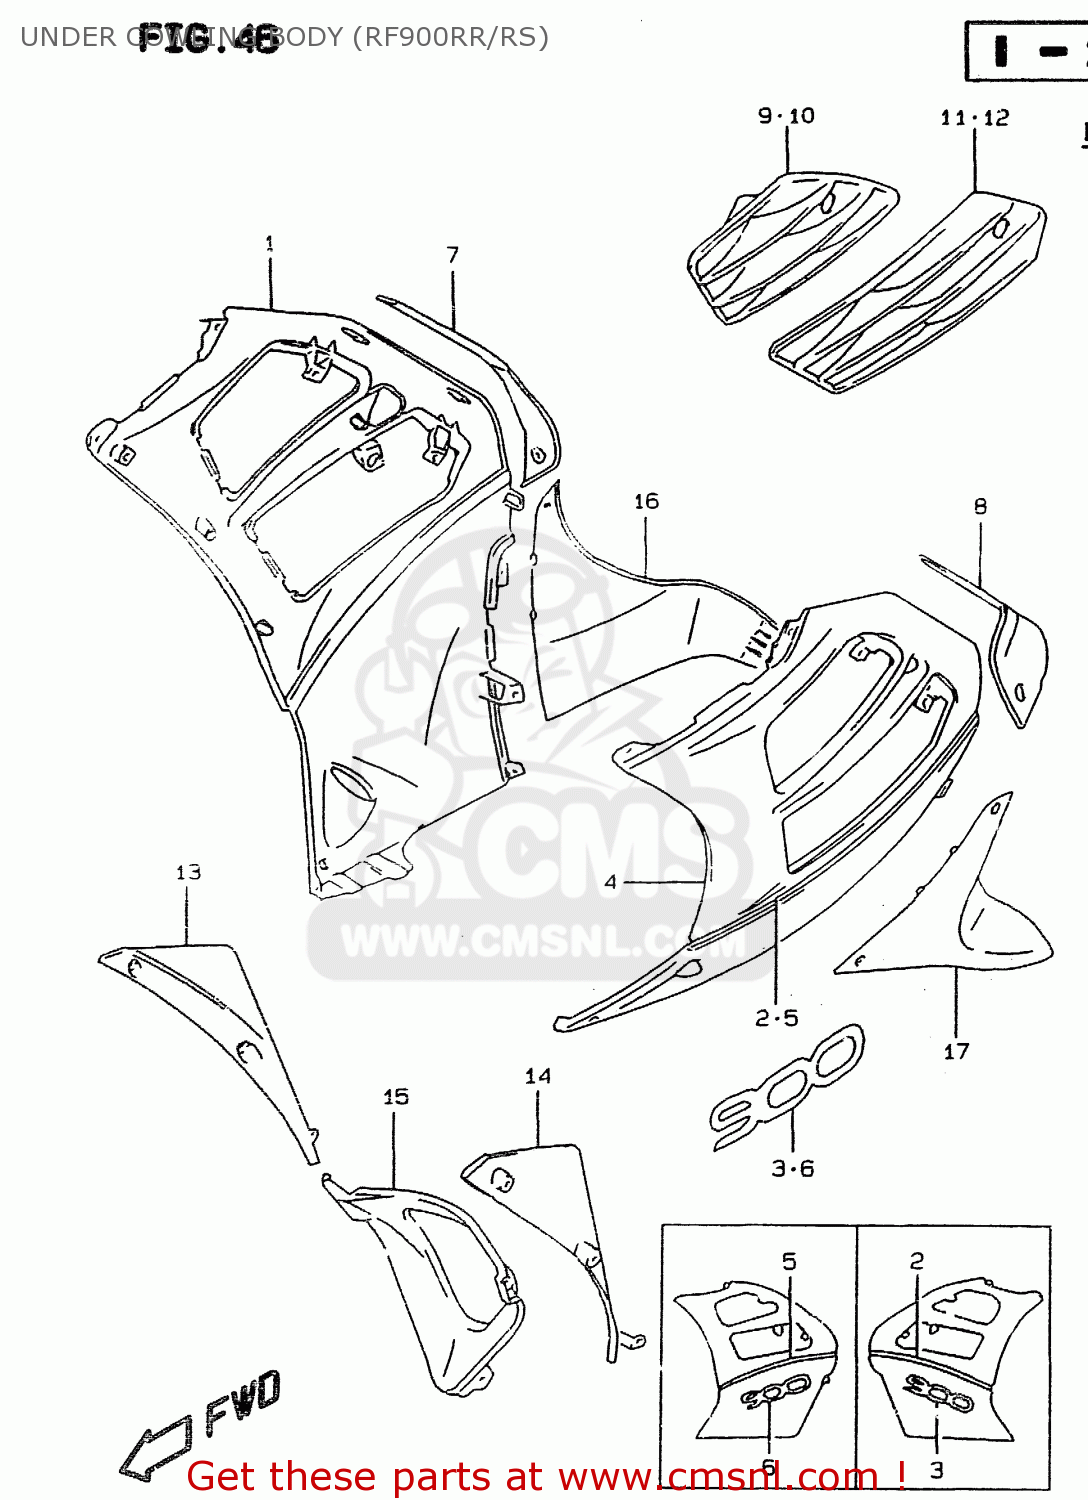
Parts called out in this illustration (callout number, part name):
1	COWLING ASSY,UNDER,R
2	TAPE,UNDER COWL,R
3	EMBLEM,COWLING UNDER
4	COWLING ASSY,UNDER,L
5	TAPE,UNDER COWLING,LEFT
6	EMBLEM,COWLING UNDER
7	PANEL,UNDER,R
8	PANEL,UNDER,L
9	COVER,UNDER COWL UPR,R
10	COVER,UNDER COWL UPR,L
11	COVER,UNDER COWL LWR,R
12	COVER,UNDER COWL LWR,L
13	COWLING,UNDER INNER,R
14	COWLING,UNDER INNER,L
15	COWLING,UNDER CTR
16	COWLING,UNDER RR,R
17	COWLING,UNDER RR,L
